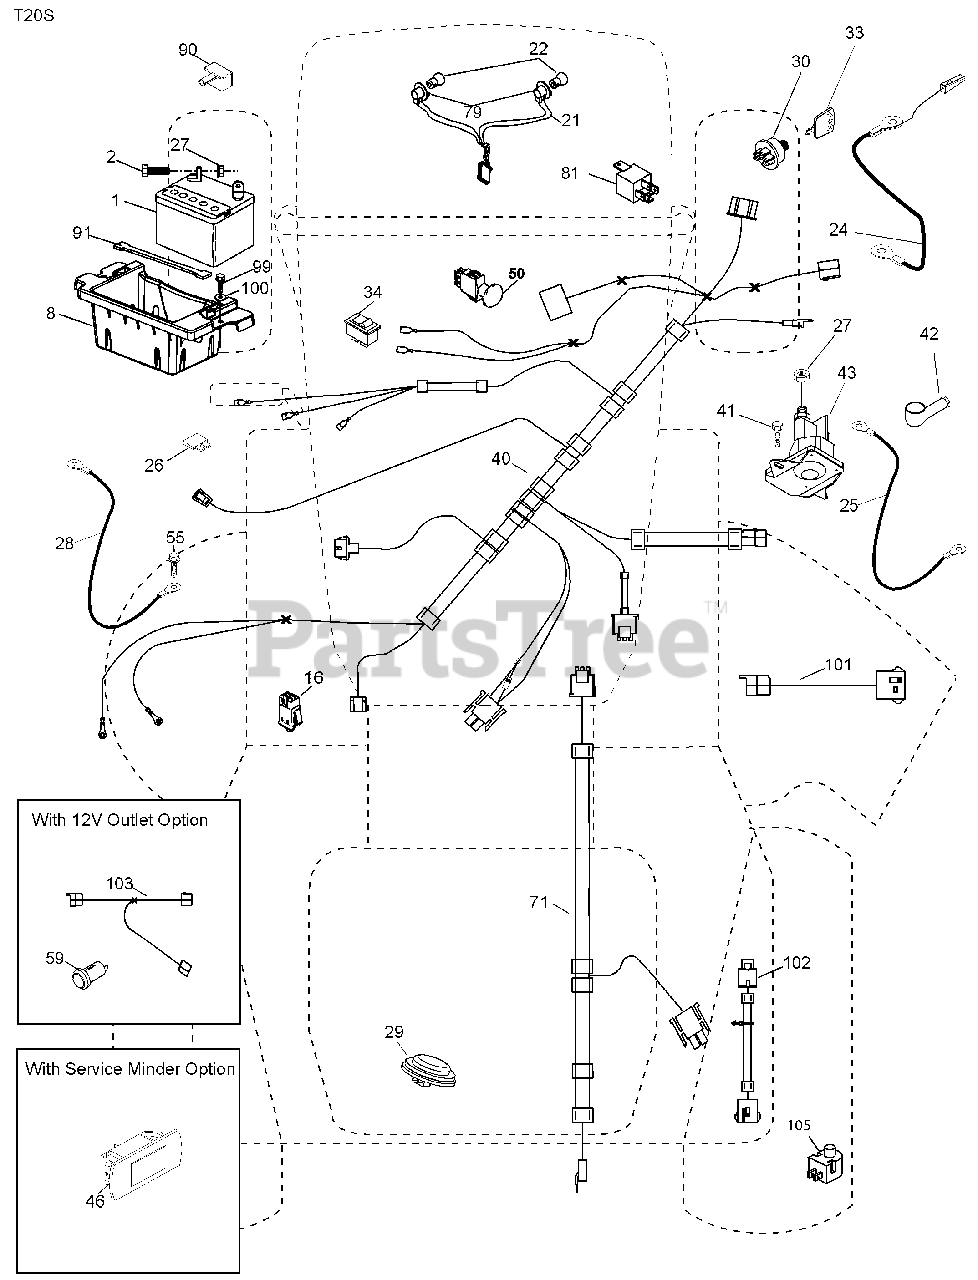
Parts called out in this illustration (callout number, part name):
1	Battery
2	Bolt Hex Hd 1/4-20 unc x 3/4
8	Battery Box
16	Switch Interlock
21	Harness Socket Light
22	Bulb, Light # 1156
24	Cable Battery
25	Cable Starter
27	Nut Keps Hex 1/4-20 unc
28	Cable Ground 21" Blk 6 Ga.
29	Switch Seat
30	Switch Ign
34	Switch Light/Reset
40	Harness Ign
41	Screw Thd Cut 1/4-20 x 1/2
42	Cover Terminal Red
43	Solenoid
46	Gauge Hourmeter
50	Switch PTO
55	Screw Thdrol 5/16-18 x 3/4
59	Outlet 12-Volt
71	Harness Ign. Chassis
79	Socket Asm Bulb
81	Relay Harness Sealed
90	Cover Terminal Battery
91	Strap Battery
99	Screw Hexwsh Thdrol 1/4-20 x 3/4
100	Washer 9/32 x 7/8 x 16 Ga.
101	Pigtail Malnlk
102	Harness Pigtail
103	Harness Pigtail
105	Switch Reverse TT Pedal
